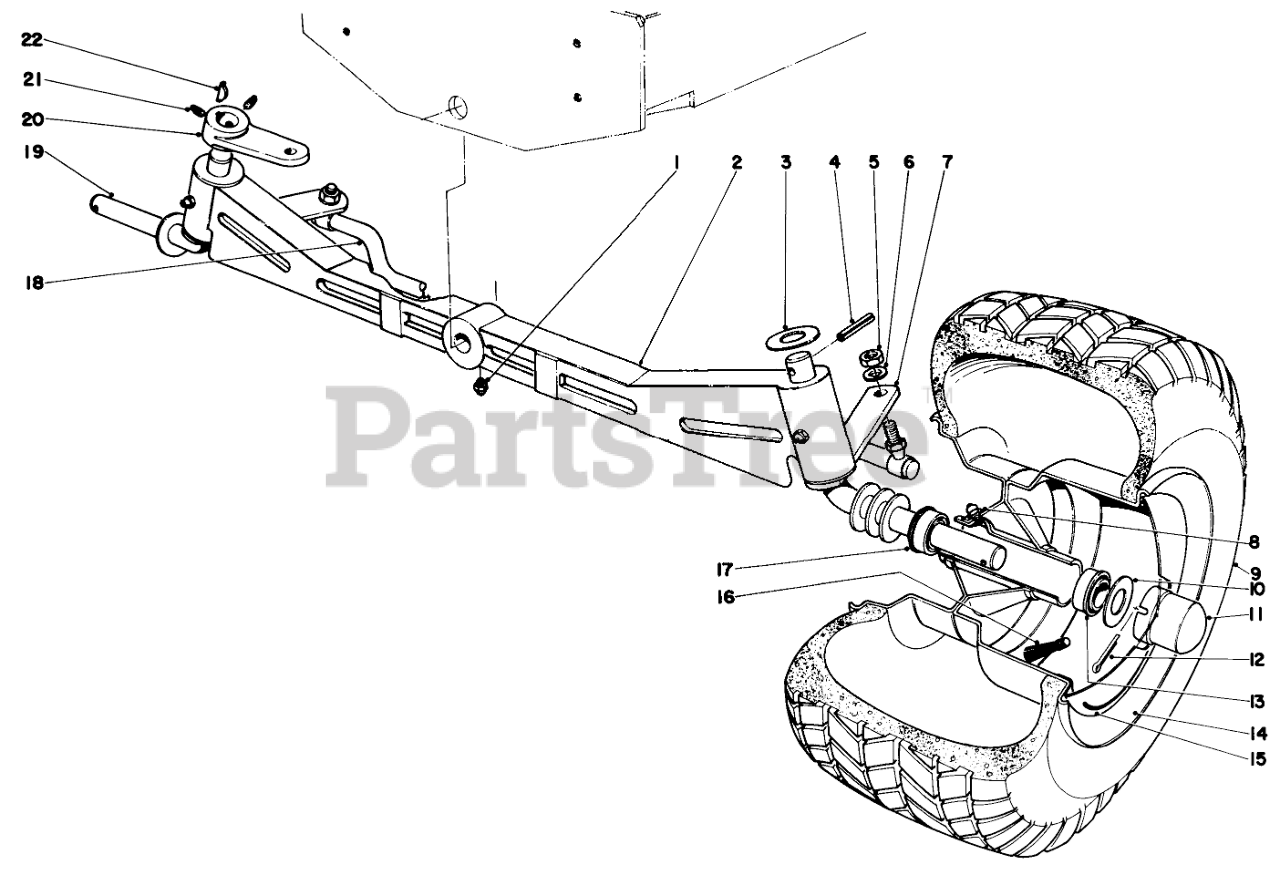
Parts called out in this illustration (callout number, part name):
1	Zerk Fitting
2	Front Axle Housing
3	WASHER-FLAT
4	PIN-ROLL
5	NUT-HEX
6	WASHER-LOCK
7	Axle Assy., L.H.
8	FITTING-GREASE
9	Tire
10	WASHER-FLAT
11	Hub Cap
12	PIN-COTTER
13	Bearing, Outer
15	Hub Cap 960
16	VALVE -STEM
17	Bearing, Inner
18	Tie Rod
19	Axle Assy., R.H.
20	Steering Lever
21	SCREW-SQH
22	KEY-WOODRUFF
